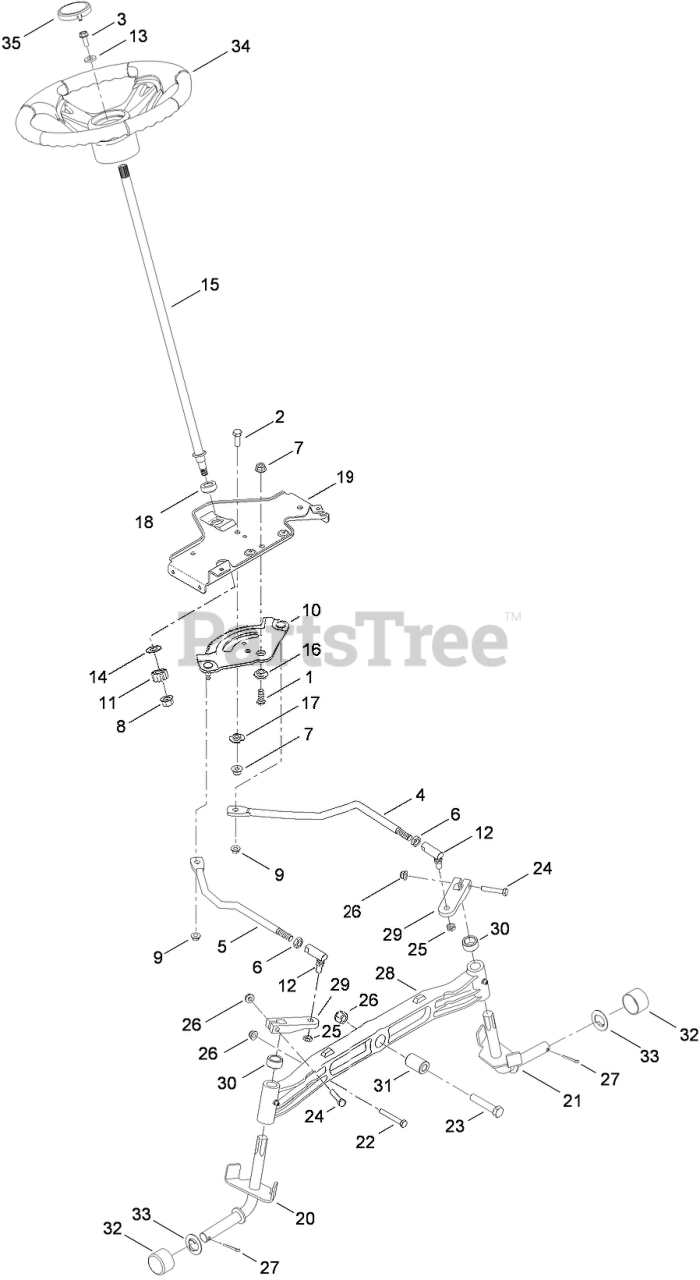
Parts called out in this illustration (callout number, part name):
1	SCREW-HH
2	SCREW-HH
3	SCREW-HH
4	LINK-DRAG, LH
5	LINK-DRAG, RH
6	NUT-JAM
7	NUT-LOCK, FLANGE
8	NUT-LOCK, FLANGE
9	NUT-LOCK, FLANGE
10	GEAR-STEERING
11	GEAR-PINION, STEERING
12	BALL JOINT ASM
13	WASHER-FLAT
14	WASHER-FLAT
15	SHAFT-STEERING
16	SPACER-SHOULDER
17	SPACER
18	BEARING-FLANGE, HEX
19	BRACKET-SUPPORT, STEERING
20	RH AXLE ASM
21	LH AXLE ASM
22	SCREW-HH
23	SCREW-HH
24	BOLT-HH
25	NUT-HEX, LOCK
26	NUT-LOCK, FLANGE
27	PIN-COTTER
28	AXLE-CAST
29	BLOCK-STEERING
30	SPACER
31	SPACER
32	CAP-HUB
33	WASHER-FLAT
34	STEERING WHEEL ASM
35	CAP-WHEEL, STEERING
